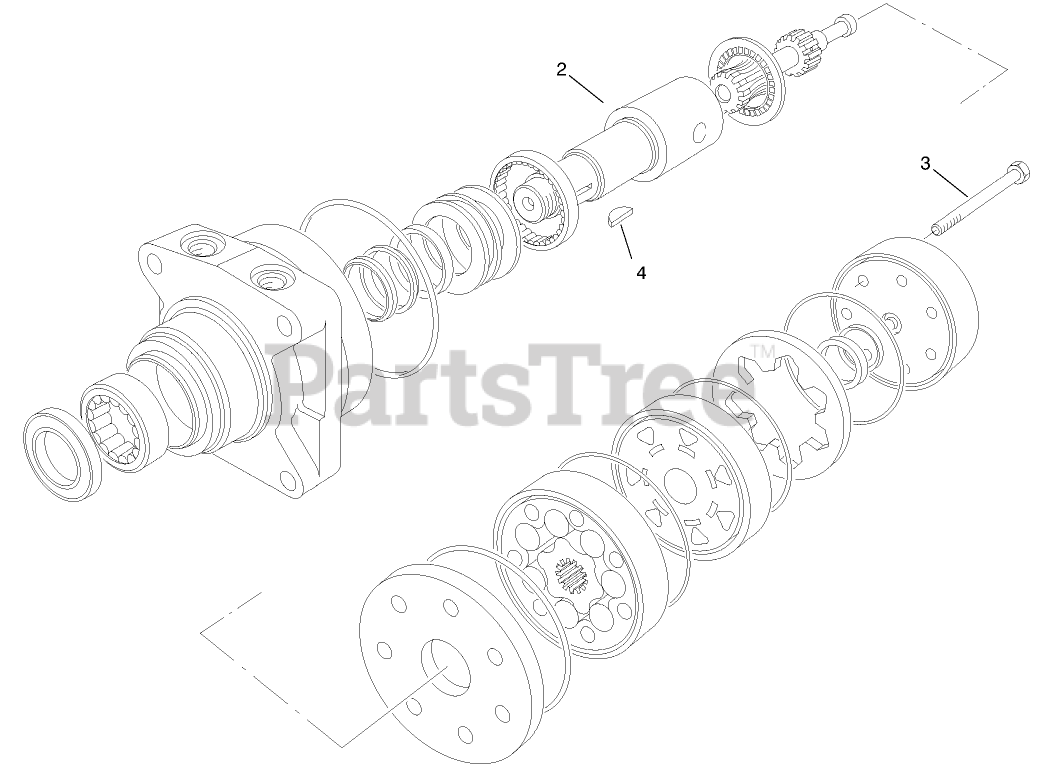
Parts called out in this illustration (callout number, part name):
2	SHAFT-COUPLING
3	SCREW-CAP, HH
4	KEY-WOODRUFF
